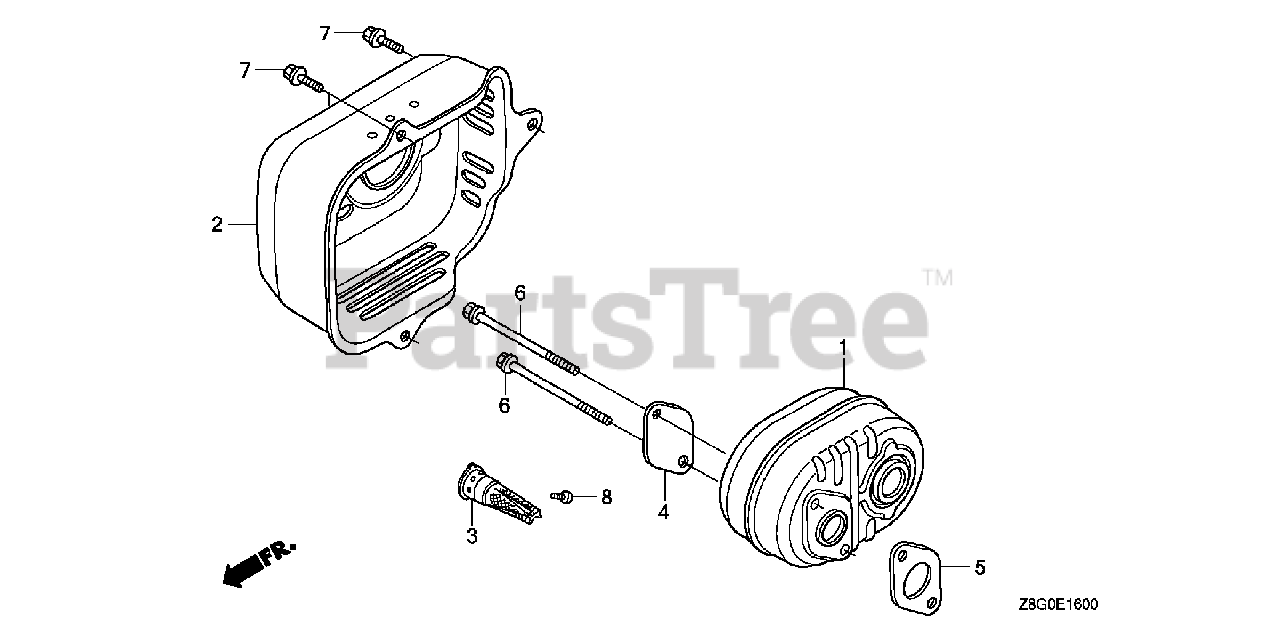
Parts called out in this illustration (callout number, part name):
1	MUFFLER
2	PROTECTOR, MUFFLER
3	ARRESTER, SPARK
4	PLATE, ARRESTER NUMBER
5	GASKET, MUFFLER
6	BOLT, FLANGE (6X79) (CT200)
7	BOLT, FLANGE (6X12) (CT200)
8	SCREW, TAPPING (4X6)
